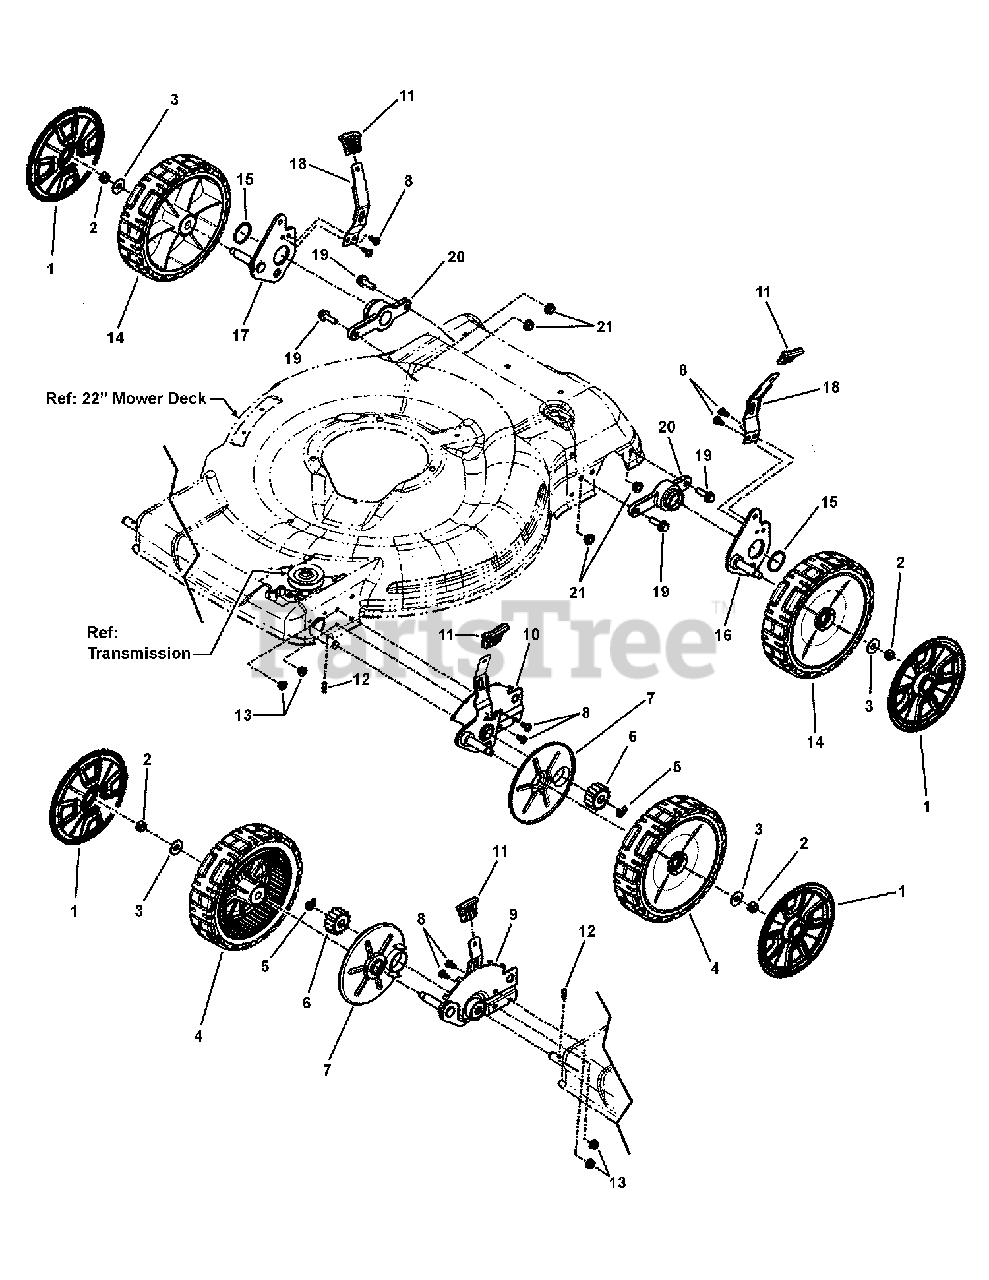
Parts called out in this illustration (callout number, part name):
1	HUBCAP, 8" & 9" Spoked Wheel, Snapper Cool Gray
2	NUT, 3/8-16 Hex Center Lock, GR 5, YZ
3	WASHER, 1" O.D. x .387 I.D., Flat
4	WHEEL, 8 x 2" Drive w/Bushing, Snapper
5	RETAINING RING, .392 Ext.
6	GEAR, Pinion, 22" WBM, Front Wheel Drive
7	SHIELD, Dust, 22" WBM, Front Wheel Drive
8	SCREW, 1/4-20 x .550" Pan Head Self-Tap (Torx)
9	ASSEMBLY, Height-of-Cut, RF, Propelled
10	ASSEMBLY, Height-of-Cut, LF, Propelled
11	GRIP, Height Latch - Black (1.7" Wide)
12	DRIVE PIN, 22" WBM
13	NUT, 1/4-20 Hex Flange Lock, YZ
14	WHEEL, 8 x 2" Idle w/Bushing, Snapper
15	SNAP RING, 1-3/8"
16	ASSEMBLY, Rear Axle, LH
17	ASSEMBLY, Rear Axle, RH
18	LEVER, Rear, 4 Point HOC
19	BOLT, 5/16-18 x 1" Hex Flange lock, GR 5, YZ
20	HOLDER, Bearing
21	NUT, 5/16-18 Hex Flange Lock, GR 5, YZ
